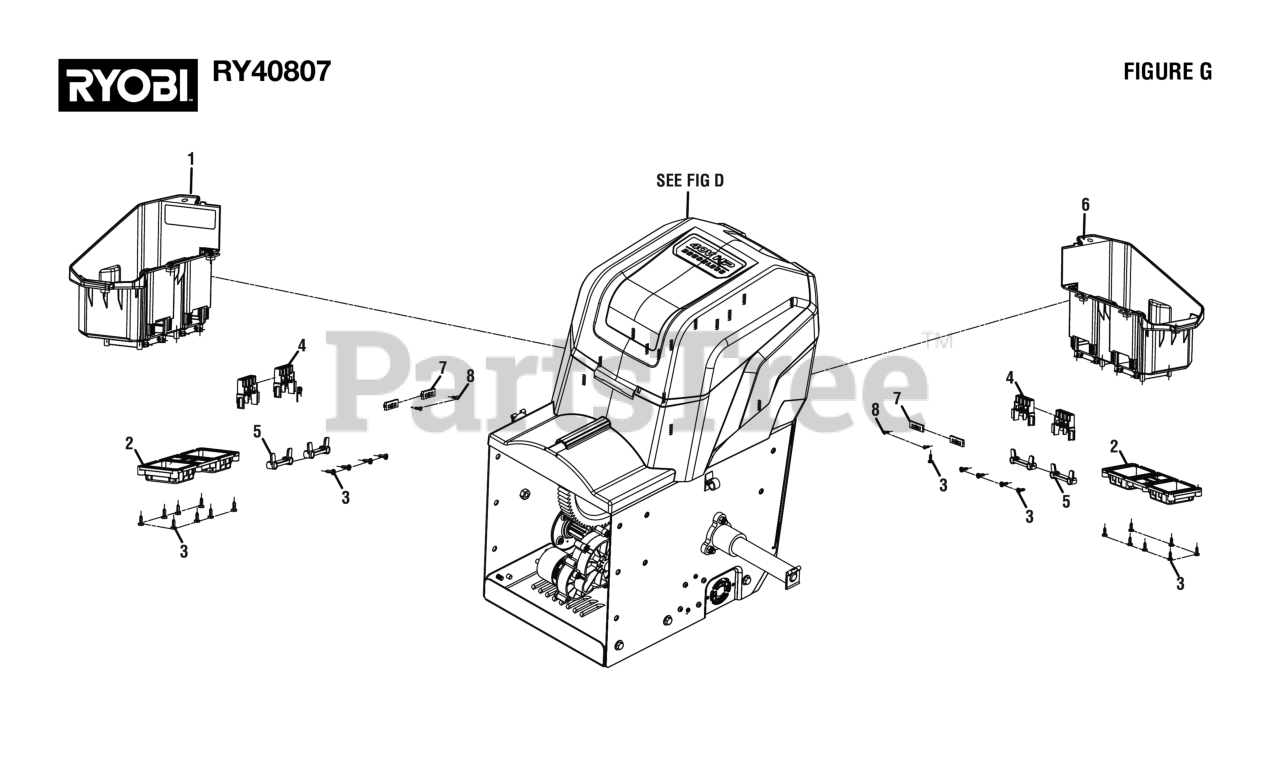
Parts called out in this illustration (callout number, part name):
1	Battery Box Assembly
2	Spring Retainer
3	Screw (M4.2 x 12 mm, T20 Torx Pan Hd.)
4	Battery Connector
5	Terminal Block Holder
6	Battery Box Assembly
7	PLASTIC, BATTERY COVER CONNECTOR,
8	Screw (M3 x 8 mm, Pan Hd., Pan Hd)
